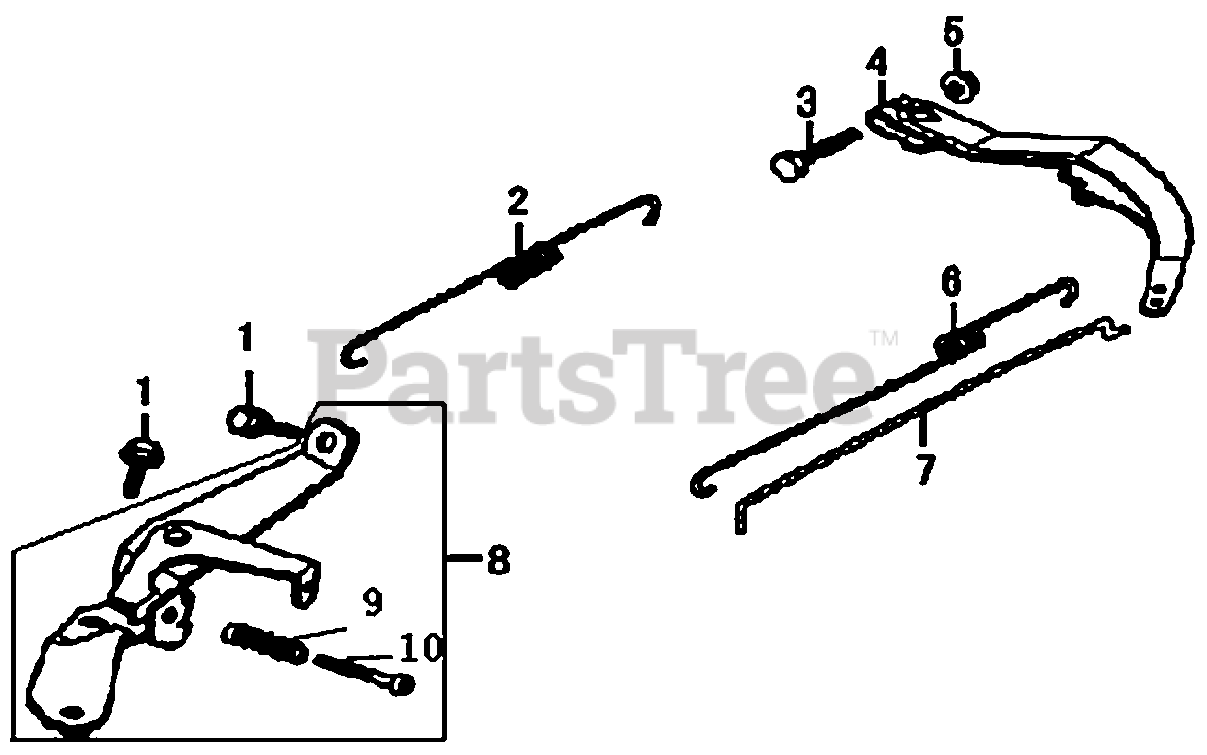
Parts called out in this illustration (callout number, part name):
1	BOLT, FLANGE, 6X10
2	SPRING, GOVERNOR
3	BOLT, QUADRATE HEAD
4	ARM, GOVERNOR
5	NUT, FLANGE
6	SPRING, THROTTLE RETURN
7	ROD, GOVERNOR
8	RETAINER, CONTROL ASSY.
10	SCREW, 5X35
